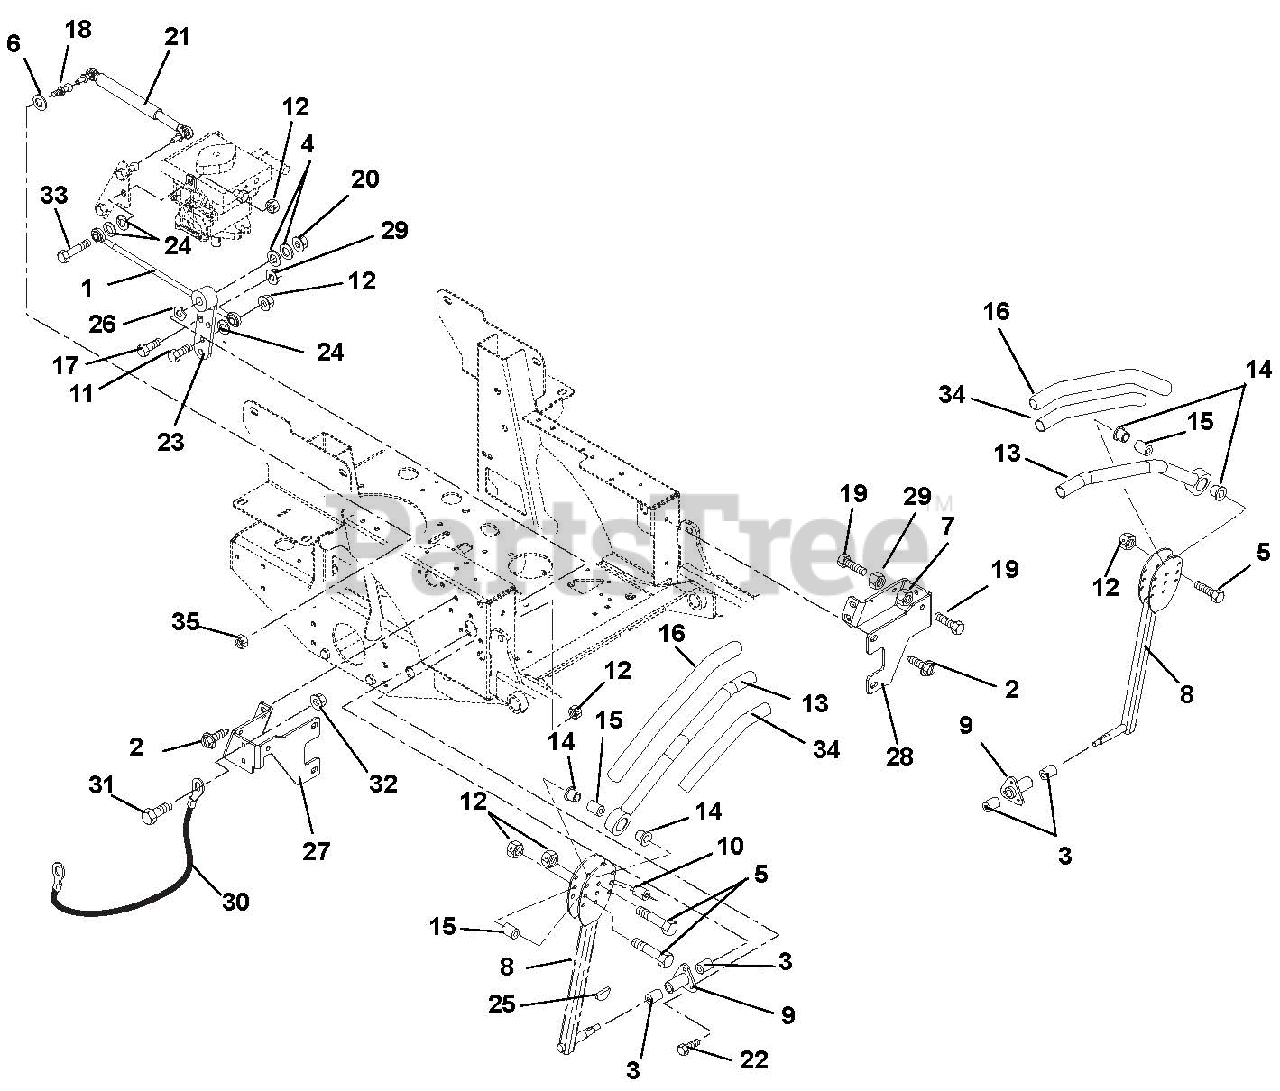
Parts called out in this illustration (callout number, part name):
1	Assembly, Steering Rod
2	Screw, Tapping .38-16 x .75 Hex Washer Head
3	Bushing .625 x .75 x .50
4	Washer, Flat Steel .406 x .812 x .065
5	Bolt, Hex .31-18 x 1.75 Grade 5
6	Washer, Flat Steel .344 x .065 YWZC
7	Nut, Hex Jam .375-16
8	Control Arm
9	Housing, Bushing
10	Bushing, Eccentric .31 x .75 x .97
11	Bolt, Hex .31-18 x 1.25 Grade 5
12	Nut, Nyloc Flange .375-16
13	Handle Weldment, Left Hand
13	Handle Weldment, Right Hand
14	Bushing, Flange Nylon .762 x 1.48 x .44
16	Grip, Handlebar
17	Bolt, Hex .375-16 x 1.75
18	Stud, Ball
19	Bolt, Hex .38-16 x 1.25 Grade 5
20	Nut, Nyloc Flange 3/8-16
21	Damper
22	Bolt, Hex .31-18 x 1.00 Grade 5
23	Weldment, Pivot Arm
24	Washer, Locking .31 x .078 Regular
25	Key, Woodruff .13 x .63
26	Wave Washer
27	Stop, Steering, Right Hand
28	Stop, Steering, Left Hand
29	Nut, Locking Jam Center .375-16
30	Cable, Hood
31	Bolt, Hex .25-20 x .75 Grade 5
32	Nut, Nyloc Flange .25-20
33	Bolt, Hex .31-18 x 1.50 Grade 5
34	Tube, .88ID x 1.00OD x 10.75
35	Nut, Top Lock .31-18
